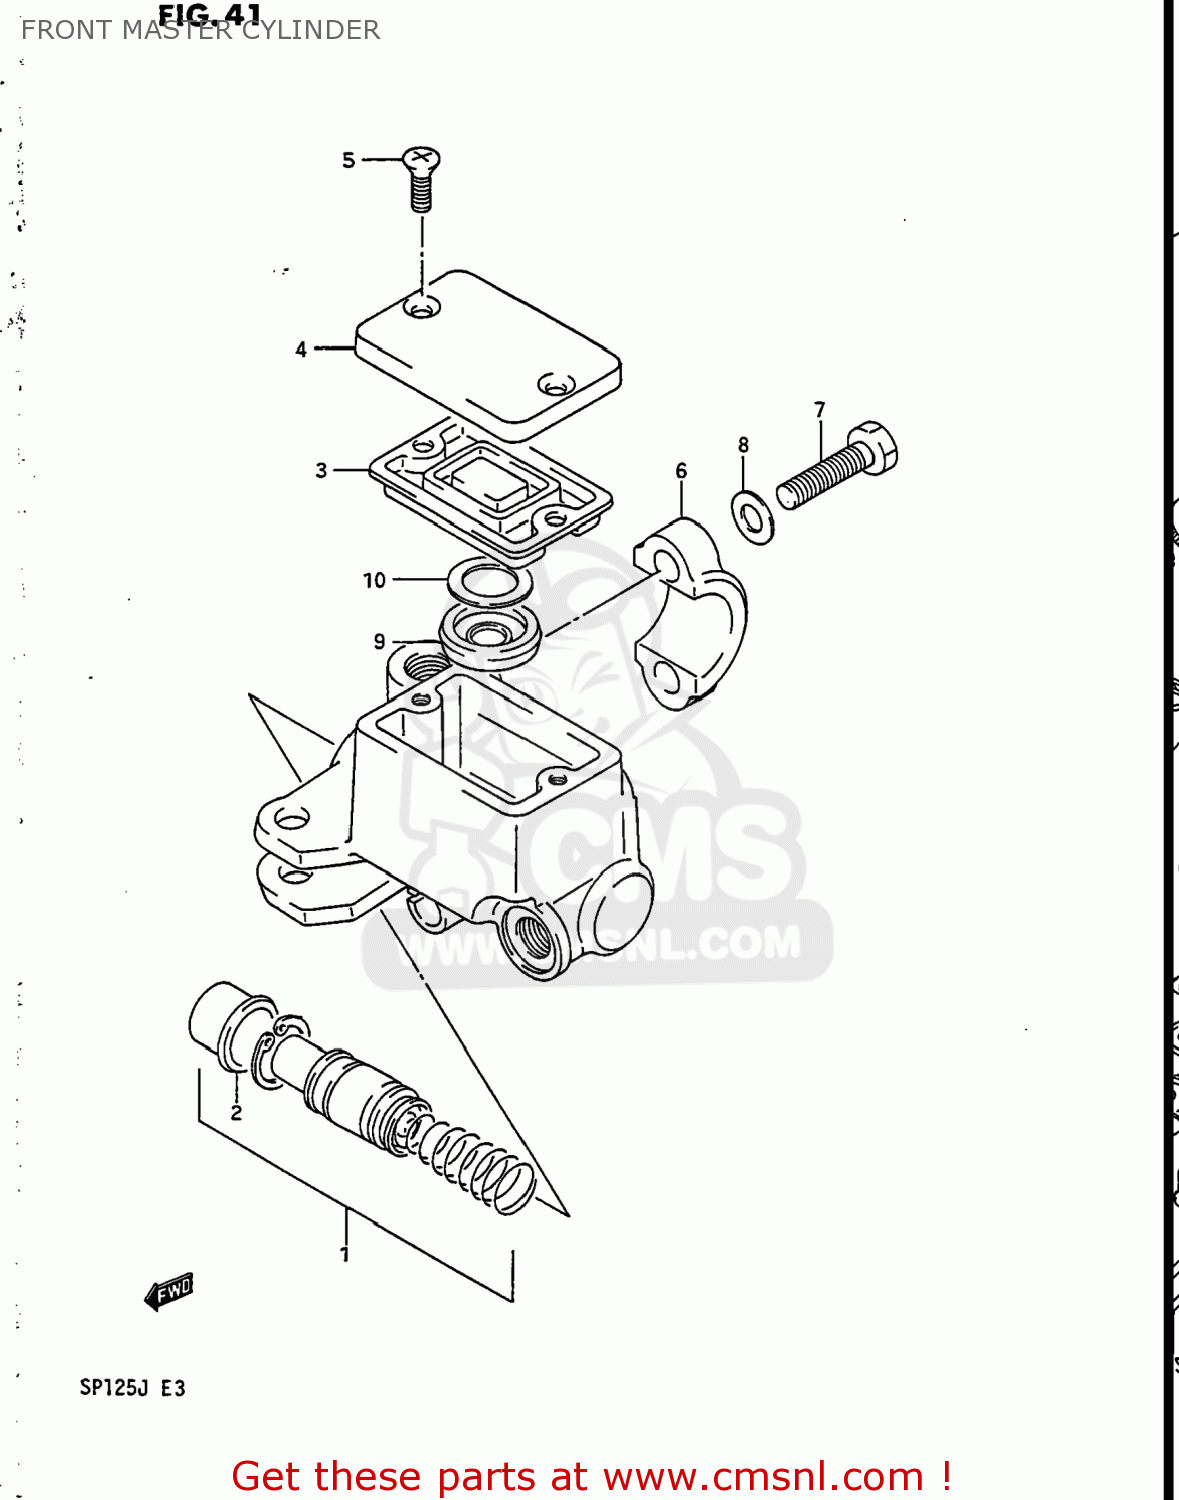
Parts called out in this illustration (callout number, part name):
1	PISTON/CUP SET
2	BOOT
3	DIAPHRAGM
4	CAP
5	SCREW
6	HOLDER
7	BOLT
8	WASHER
9	SEPERATOR
10	PLATE
